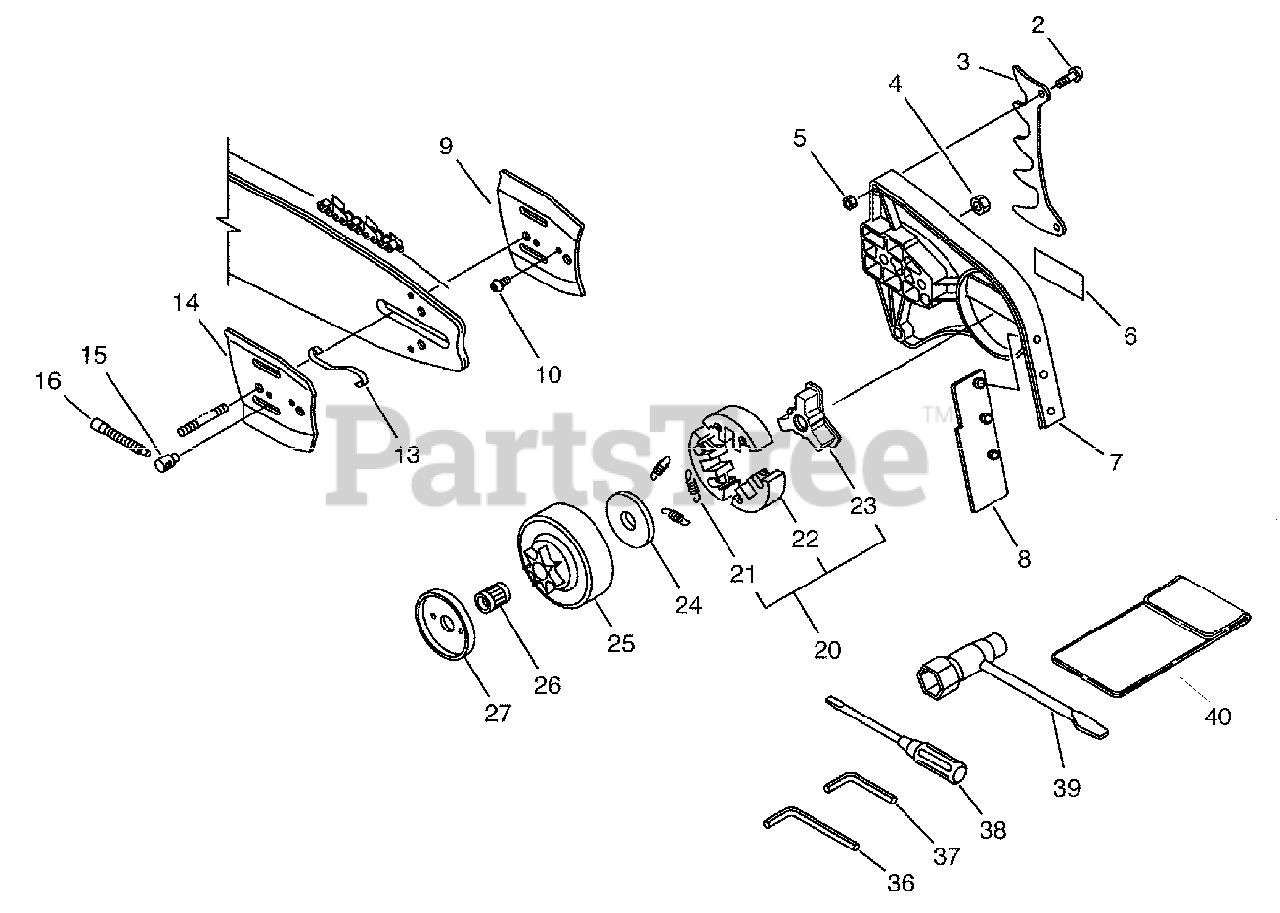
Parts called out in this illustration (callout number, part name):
2	SCREW - 6X20
4	NUT
5	LOCKNUT - 6
6	LABEL - ECHO
7	GUARD, SPROCKET
9	PLATE, GUIDE - OUTER
10	SCREW - 3X6
13	HOLDER, PLATE
14	PLATE, GUIDE - INNER
15	TENSIONER, CHAIN
16	SCREW, TENSIONER
20	CLUTCH ASSY
21	SPRING, CLUTCH
22	CLUTCH SHOE SET
23	HUB, CLUTCH
24	PLATE, CLUTCH
25	DRUM, CLUTCH
26	BEARING, NEEDLE
36	HEX KEY - 6mm
37	HEX KEY - 4mm
38	SCREWDRIVER
39	T-WRENCH - 17X19mm
40	BAG, TOOL
